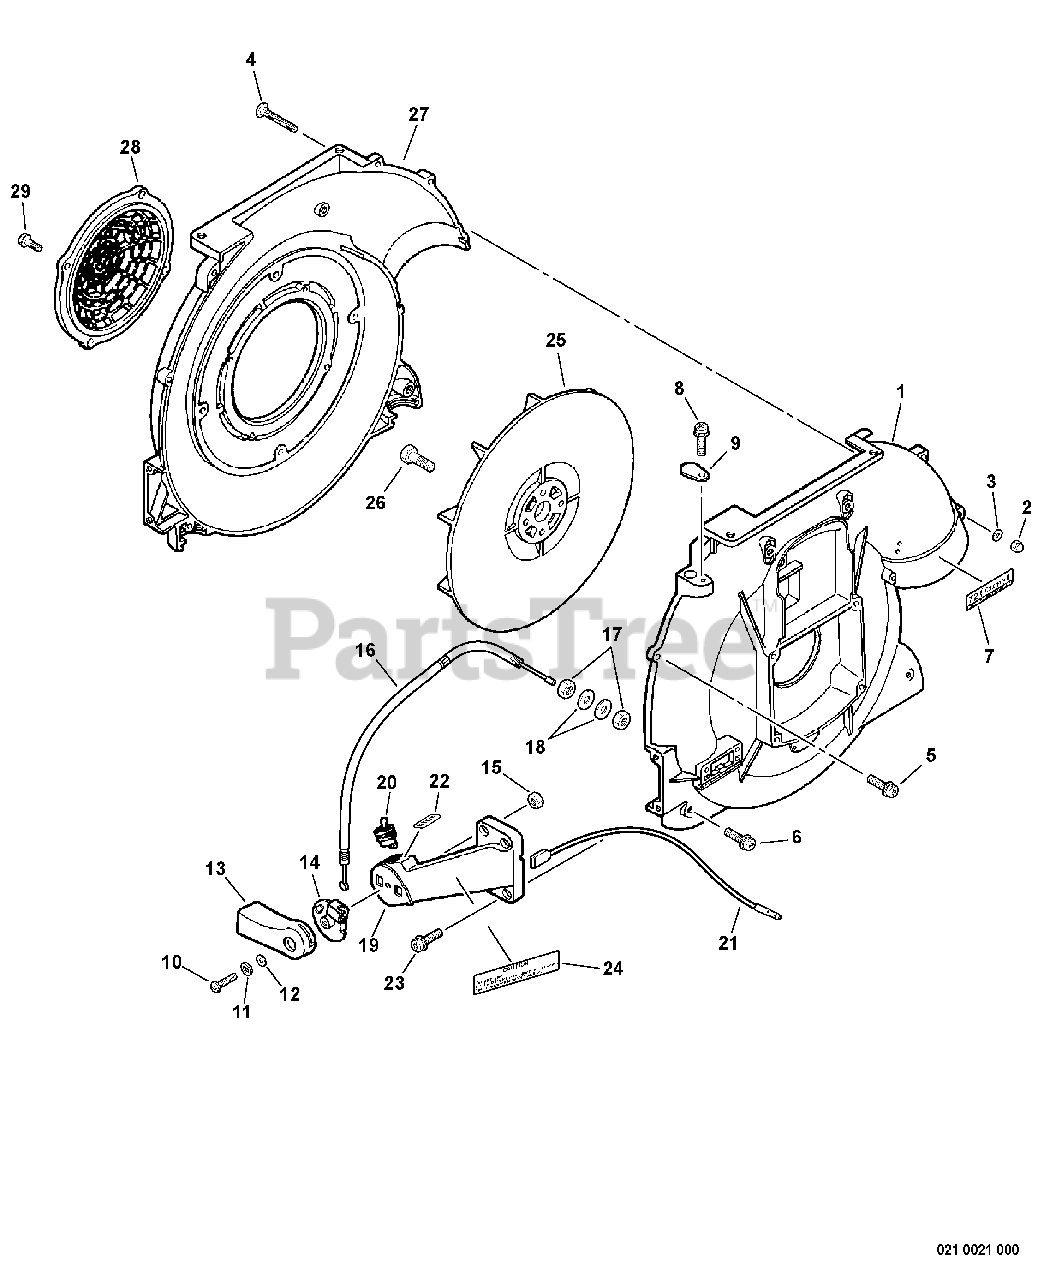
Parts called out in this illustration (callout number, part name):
1	COVER, FAN - OUTER
2	NUT - 5 -- CAP
3	WASHER - 5
4	BOLT, ELBOW
5	SCREW - 5X20
6	SCREW - 5X25
7	LABEL - NOISE 72dB(A) CAT III
8	SCREW - 5X10
10	SCREW - 6X25
11	LOCKWASHER - 6
12	WASHER - 6
13	TRIGGER, THROTTLE
15	LOCKNUT - 6
16	CABLE, THROTTLE
18	WASHER - 6
19	MOUNT, THROTTLE LEVER
20	IGNITION SWITCH ASSY
22	LABEL - STOP
23	SCREW - 5X20
24	LABEL - CAUTION
26	BOLT - 5X16
27	COVER, FAN - INNER -- ORANGE
28	GUARD, DEBRIS
29	BOLT - 6X14
